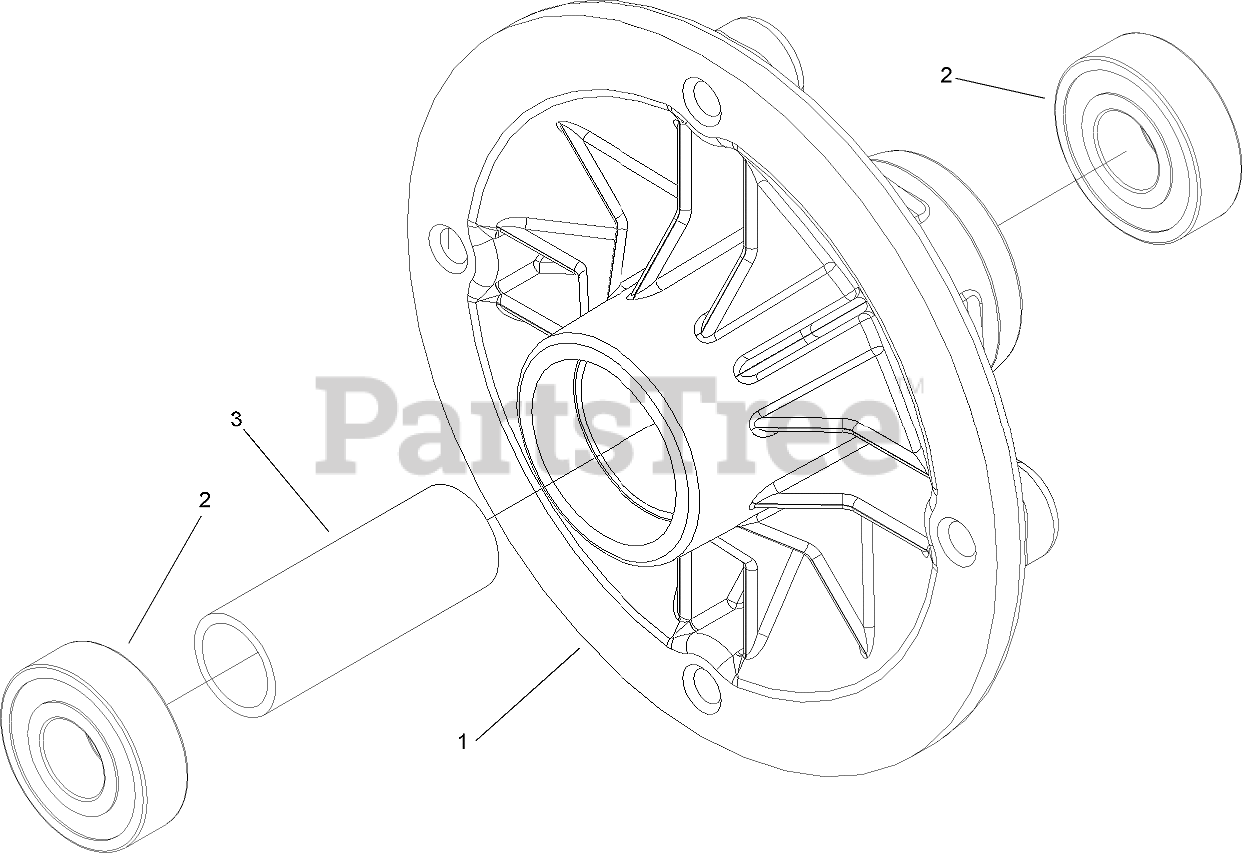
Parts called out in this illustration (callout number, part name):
1	HOUSING-SPINDLE
2	BEARING-BALL
3	SPACER
